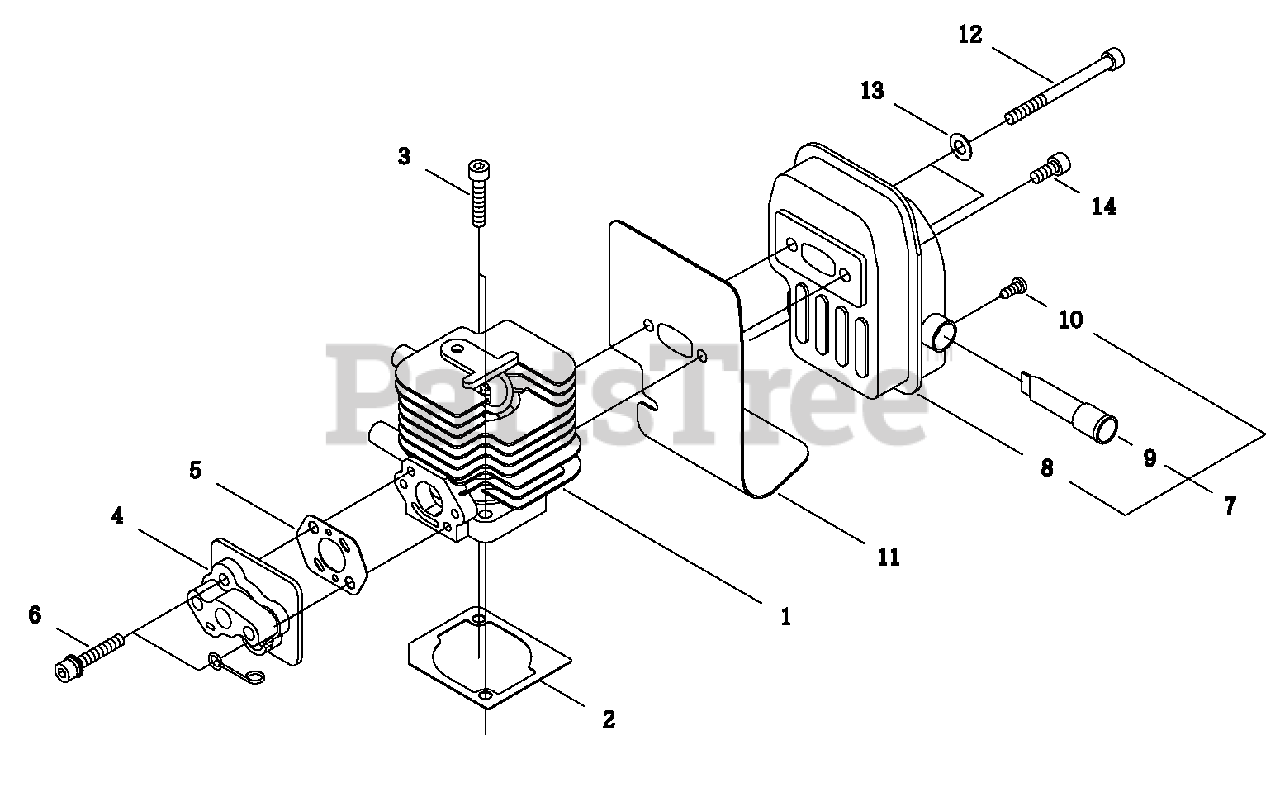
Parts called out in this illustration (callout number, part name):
1	CYLINDER
2	GASKET, CYLINDER
3	BOLT 5×25
4	INSULATOR, INTAKE
5	GASKET, INTAKE
6	BOLT M5×30
7	MUFFLER ASSY
8	MUFFLER
9	SCREEN, SPARK ARRESTER
10	SCREW, TAPPING 3×6
11	HEAT SHIELD, EXHAUST
12	BOLT M5×50
13	WASHER, FLAT 5.5×10×0.8
14	BOLT 5×12
